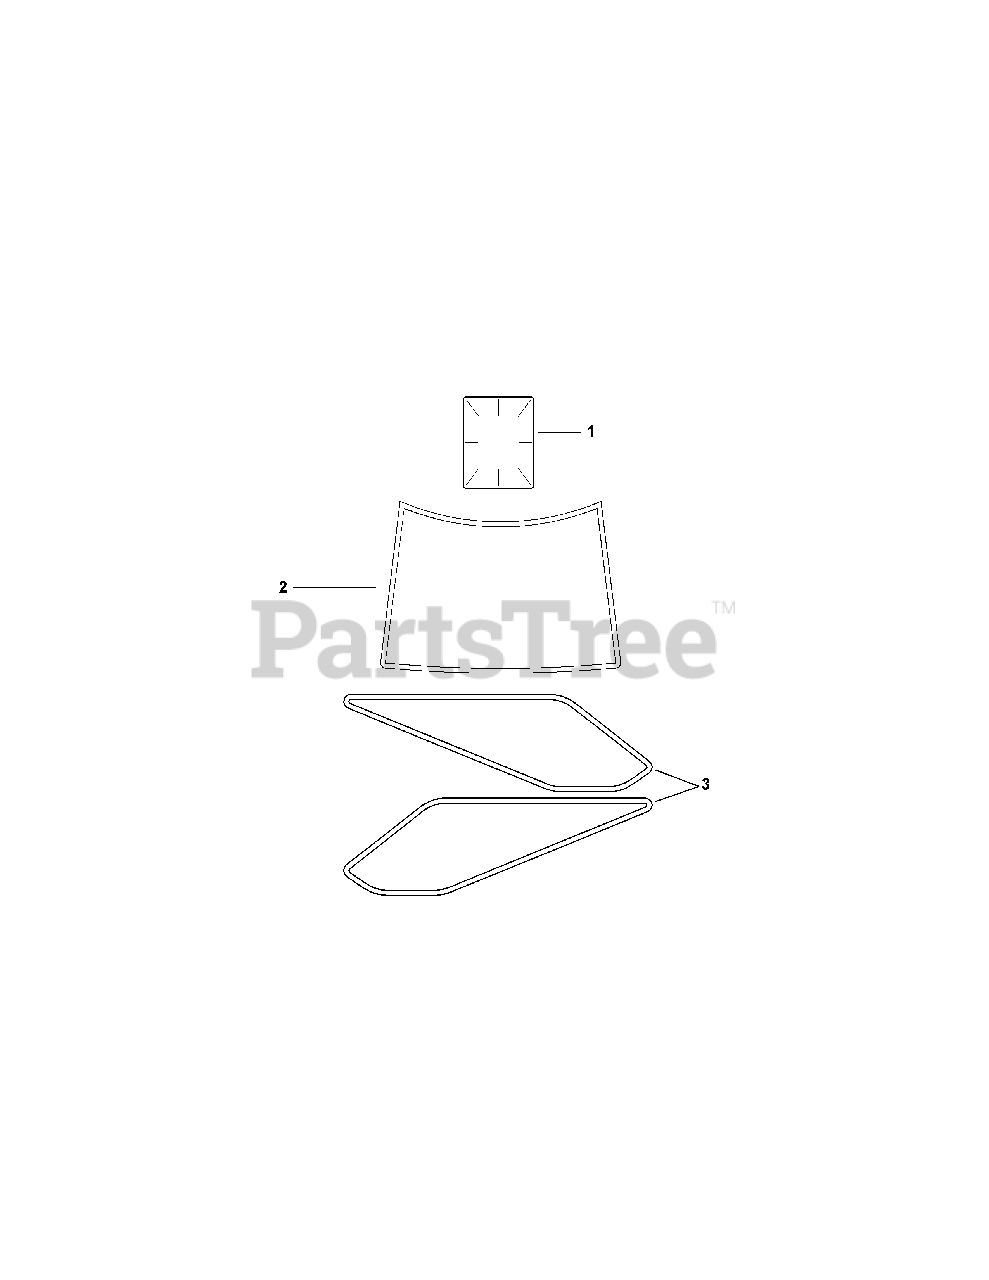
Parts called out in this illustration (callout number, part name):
1	Clear Laminate Decal
2	Decal, 22HP
3	Decal, Cub Twin Wings
